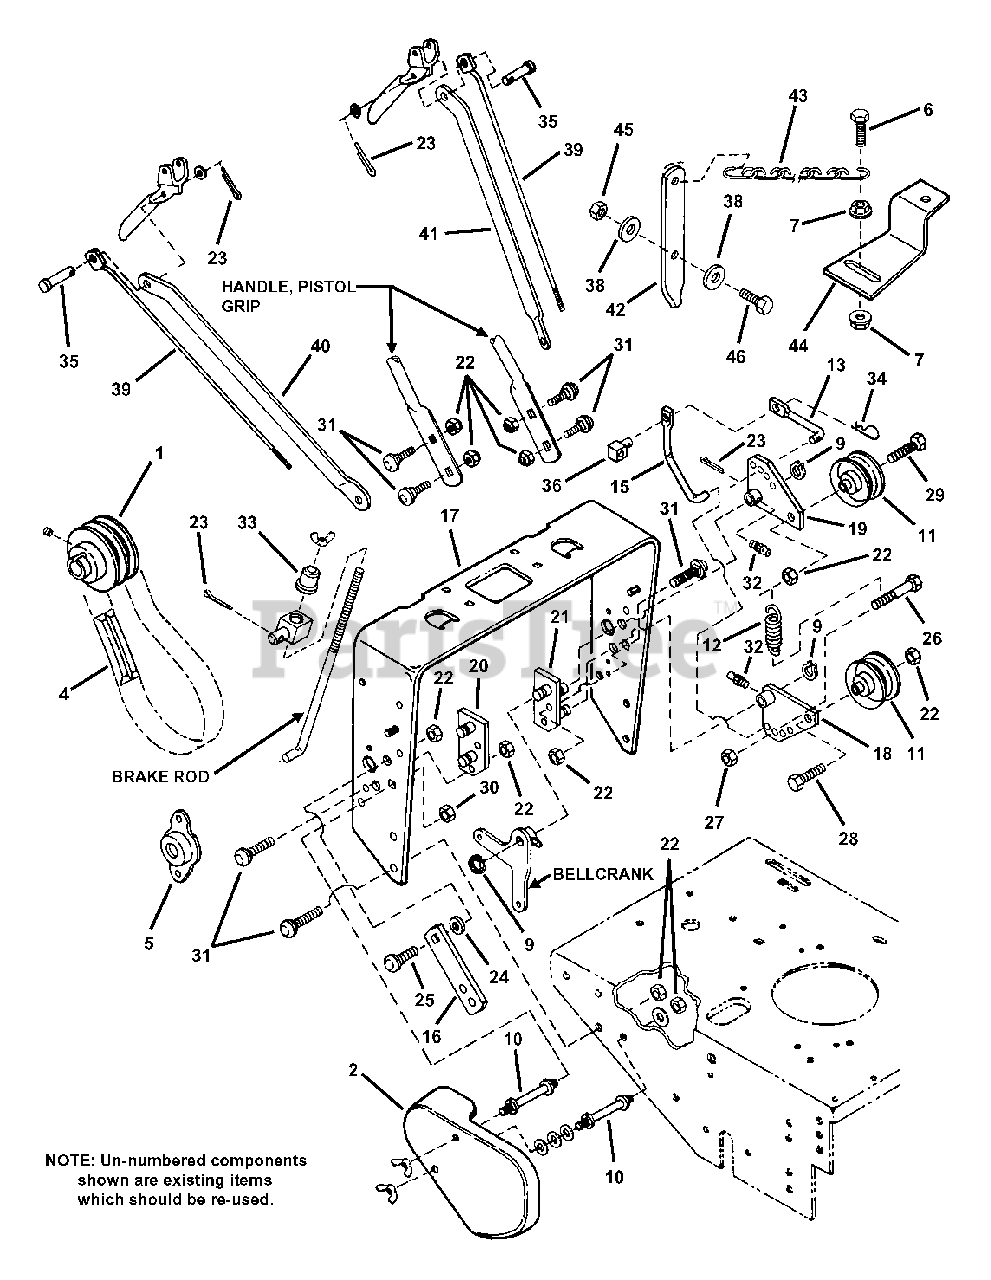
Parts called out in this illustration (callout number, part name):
1	PULLEY, 3-1/4" (transmission out)
3	FENDER, Right
4	BELT, PRO 7 Traction
5	FLANGE, Output
6	SCREW, 1/4-20 x 1" Hex Head Cap, Grade 5
7	NUT, 1/4-20 Hex Flange Lock
8	ASSEMBLY, Tank Bracket
9	RING, 5/8" External Retaining
10	STUD, Fender Mount (3/8-16 thread)
11	PULLEY, 3-1/4" Idler
12	SPRING, Extension
13	LINK, Short
15	LINK, Long Left Hand
16	ARM, Brake
17	FORM, Tank Bracket
18	WELDMENT, Idler Lower Left/Upper Right
19	WELDMENT, Upper Left/Lower Right
20	WELDMENT, Idler Pivot Right Hand
21	WELDMENT, Idler Pivot Left Hand
22	NUT, 3/8-16 Hex Nyloc
23	PIN, 3/32 x 1" Cotter
24	WASHER, 3/8" Flat
25	BOLT, 3/8-16 x 3/4" Square Neck, Grade 2
26	SCREW, 5/16-18 x 3/4" Hex Head Cap, Grade 5
27	NUT, 5/16-18 Hex Flange Lock
28	SCREW, 3/8-16 x 2" Hex Head Cap, Grade 5
29	SCREW, 3/8-16 x 2-1/2" Hex Head Cap, Grade 5
30	NUT, 3/8-16 Hex Jam
31	BOLT, 3/8-16 x 1" Round Head Square Neck, Grade 5
32	FITTING, Grease, 1/4-28 Thread
33	BUSHING, .381 I.D. Flange
34	PIN, #13 Hair
35	PIN, Reverse PG
36	SWIVEL, Brake Link PM
37	SCREW, 3/8-16 x 1" Hex Head Cap, Grade 5
38	WASHER, 1/4" Flat
39	ROD, Traction, Pistol Grip
40	STRAP, Brake Pistol Grip, Left Side
41	STRAP, Brake Pistol Grip, Right Side
42	LEVER, Reverse, Pistol Grip
43	CHAIN, Reverse, Pistol Grip
44	ARM, Reverse
45	NUT, M6 Hex Lock
46	SCREW, M6 x 14 Hex Head Cap
